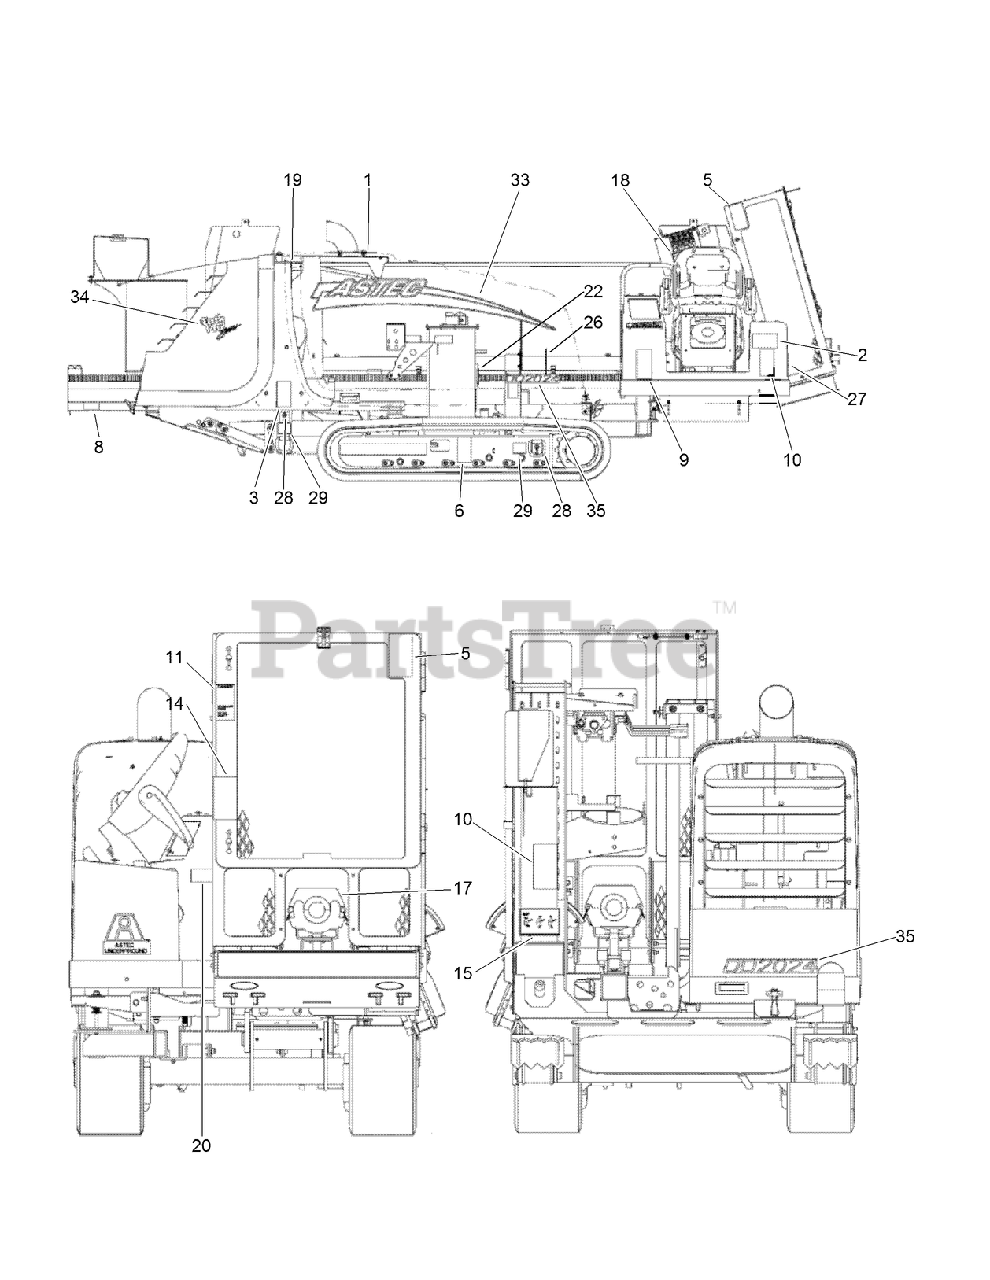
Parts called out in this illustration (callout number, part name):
1	DECAL-Hot Surface
2	DECAL - Warning, No Riders (Front), ISO
3	DECAL - Danger, Crush, Hands and Feet, ISO
5	DECAL - Warning, Stand Clear, ISO
6	DECAL - Warning, Flying Objects, ISO
8	DECAL - Danger, Crush From Above, ISO
9	DECAL - Danger, Strike Alert Electrocution Hazard, ISO
10	DECAL - Danger, Runover Hazard, ISO
11	DECAL - Danger, Vertical Auger Entanglement, ISO
14	DECAL - Do Not Use Pipe Wrench, ISO
15	DECAL - Stabilizer/Thrust Frame Setup
17	DECAL - Danger, Entanglement Hazard, Small, ISO
18	DECAL - Stakedown Setup
19	DECAL-Fan Entanglement
20	DECAL - Warning, Read Operators Manual, ISO
22	DECAL-Hydraulic Oil Level
26	DECAL - Remote Plug
27	DECAL - A, Astec Underground
28	DECAL - Lift Hook Location
29	DECAL-Tie Down
33	DECAL - Astec, Red and Blue Pattern
34	DECAL - Earth Pro, Medium Size
35	DECAL - DD-2024
